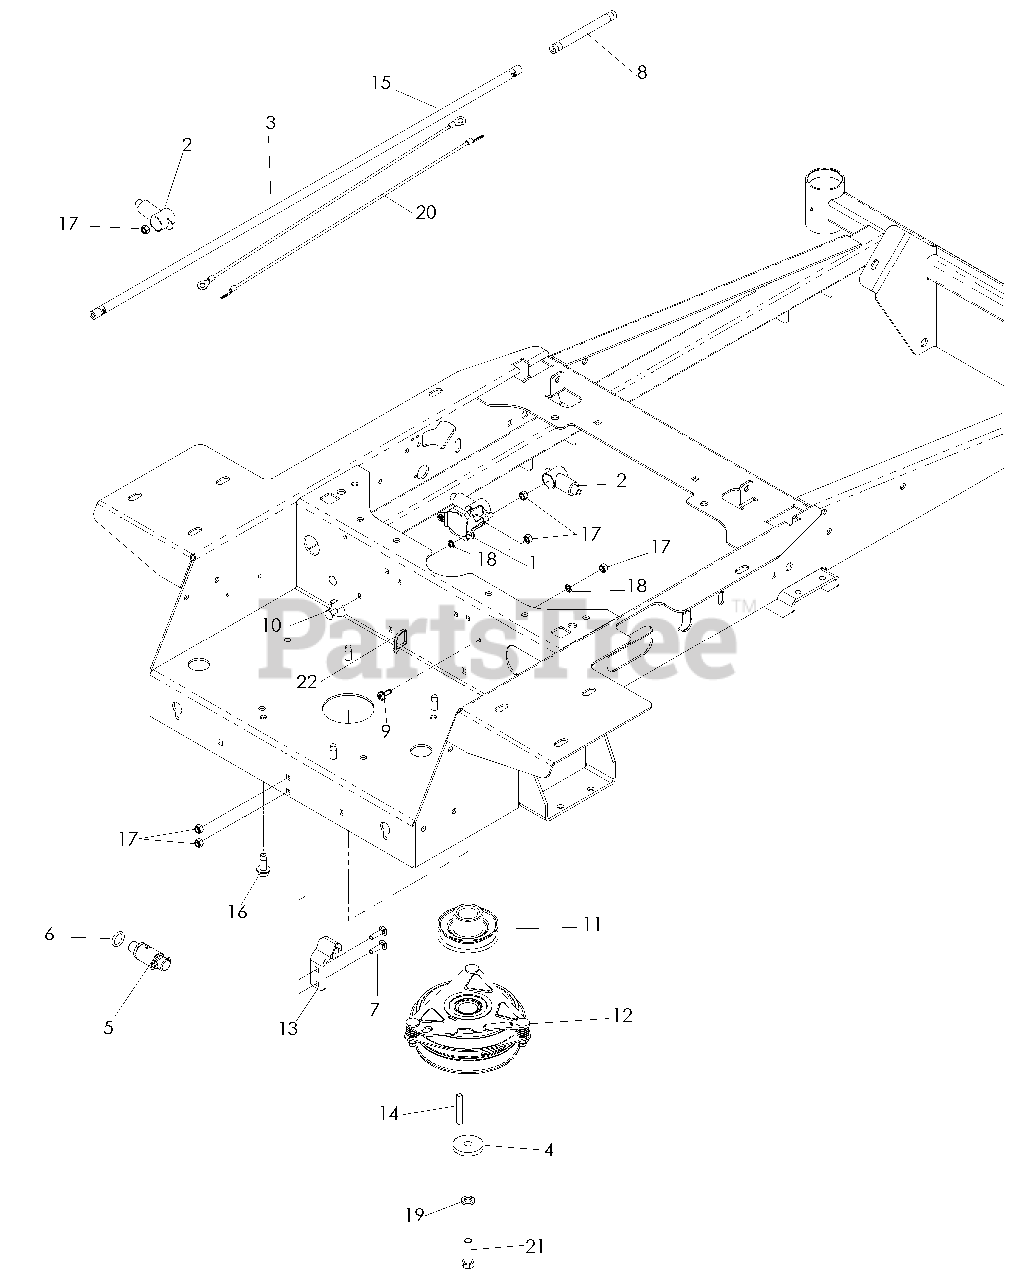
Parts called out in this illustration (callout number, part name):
2	INSULATOR, BATTERY
4	WASHER .469
5	PLUG EZ OIL DRAIN
6	WASHER 5/16 EXT STAR
7	RHSNB 1/4-20 x 1
8	FUEL LINE, 5"
9	SCREW 1/4-20 X 5/8 THDROLL
10	RHSSNB 1/4-20 x 5/8
11	PULLEY, DRIVE
13	CLUTCH TIE DOWN
14	KEY 1/4 SQ x 2
15	CLAMP, HOSE
16	BOLT 3/8-16 x 1 THD FRM
17	NUT 1/4-20 NYLOC
18	WASHER 1/4
19	WASHER 7/16
20	CABLE, POSITIVE, LONG
21	HCS 7/16-20 x 1 1/2
